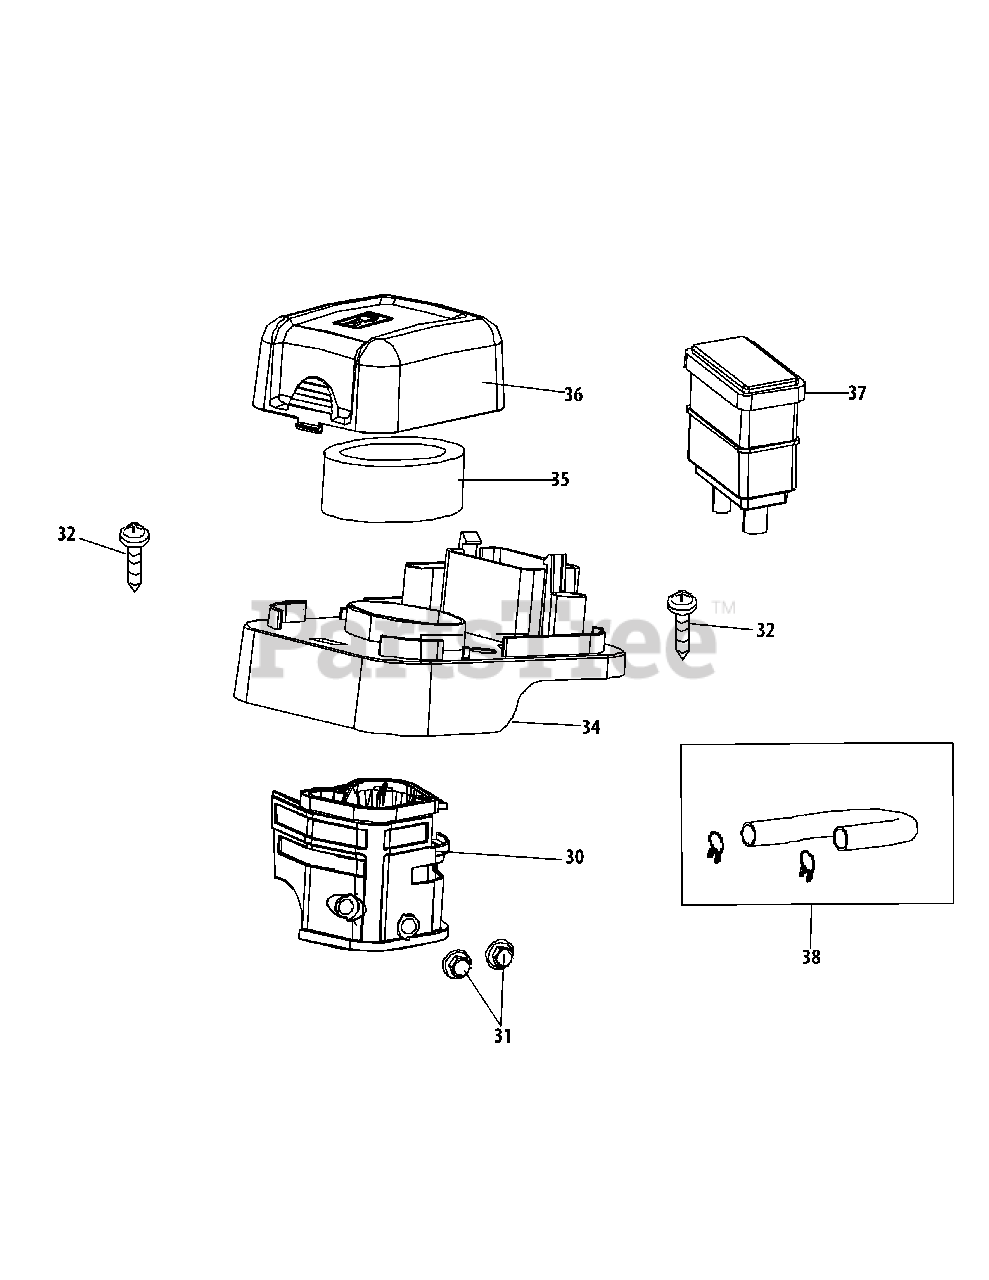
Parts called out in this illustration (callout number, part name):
30	Air Cleaner Housing
32	Self-Tapping Bolt M4.2×16
34	Silencer Plate
35	Air Cleaner Filter Assembly
36	Air Cleaner Cover
37	Carbon Canister
38	Hose Assembly
38	Clamp, Hose
